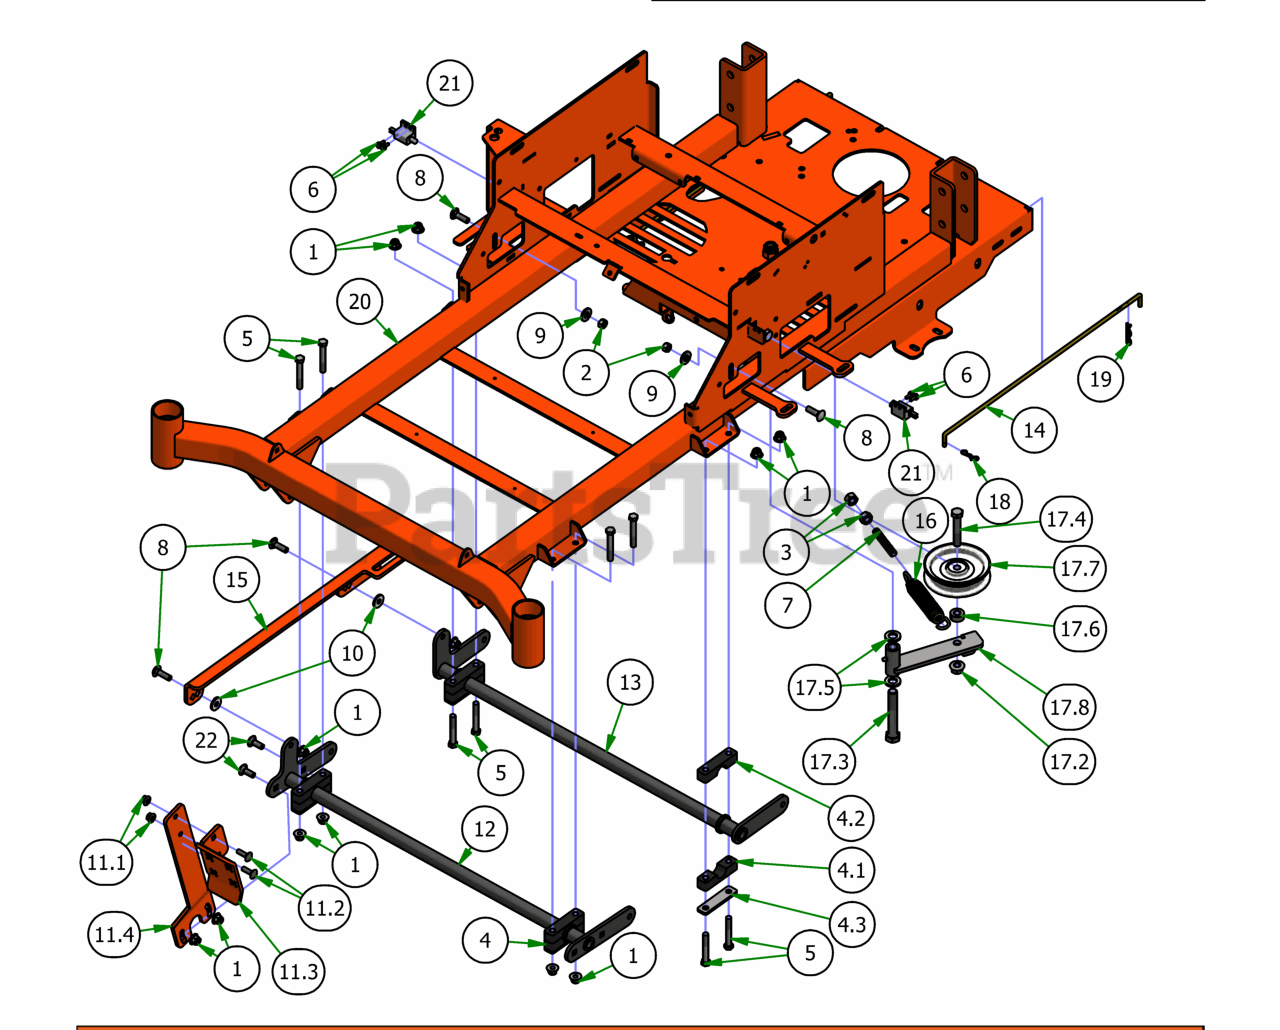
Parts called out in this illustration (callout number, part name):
1	3/8 Nylock Flange Nut
2	3/8" Hex Nut
3	1/2" Hex Nut
4	Pillow Block Kit
4.1	Pillow Block MZ male
4.2	Pillow Block MZ female
4.3	Pillow Block Strap
5	3/8-16 x 2 1/2" Hex Bolt
6	12-24x 1/2 HWH Bolt
7	All Thread-Pump Idler Tensioner
8	3/8" x 1 1/4" Carriage Bolt
9	3/8" Flat Washer
10	.360 ID Plastic Washer
11	Foot Pedal Assembly
11.1	5/16-18 NYLON INSERT FLANGE LOCKNUT ZINC
11.2	5/16-18 X 1 CARRIAGE BOLT (GR.8) ZINC
11.3	2017 MZ/ZT Shallow Foot Pedal
11.4	2017 MZ/ZT Deck Pedal Lever
12	Actuator Bar Front- 2017 MZ/ZT
13	Actuator Bar Rear- 2017 MZ/ZT
14	ZT Neutral level rod 2011
15	2017 MZ/ZT Actuator Linkage
16	Deck Idler Spring
17	ZT Pump Idler
17.1	5/8-11 NYLON INSERT JAM LOCKNUT ZINC
17.2	1/2-13 NYLON INSERT FLANGE LOCKNUT ZINC
17.3	5/8-11 X 4 HEX CAP SCREW (GR.8) ZINC YELLOW
17.4	1/2-13 X 2-3/4 HEX CAP SCREW (GR.5) ZINC
17.5	.635 ID X 1.120 OD X .140 THICK FLAT WASHER NYLON
17.6	1/2 SOLID SHAFT COLLAR (W/1 SET SCREW) ZINC
17.7	4 3/4" Idler Pulley
17.8	Pump Idler Bracket
19	Neutral Rod Clip
20	2018 Compact Outlaw Frame
21	Safety Switch
22	3/8-16 X 1 CARRIAGE BOLT (GR.5) ZINC
